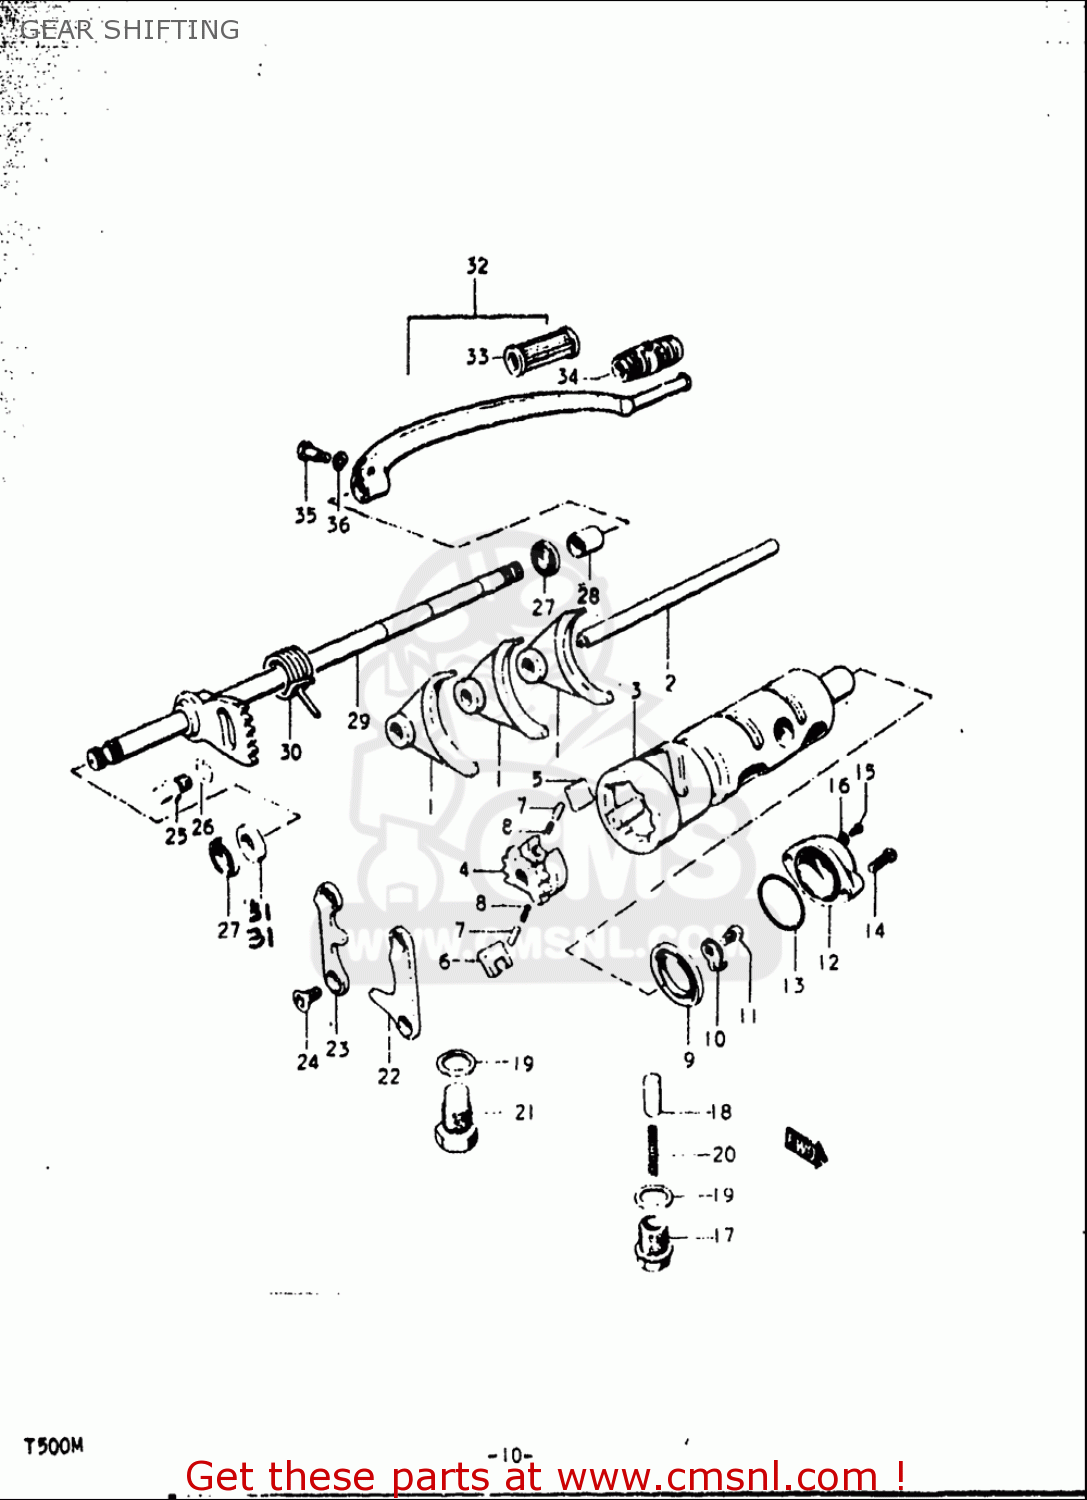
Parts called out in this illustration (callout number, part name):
4	GEAR,GEAR SHIFT CAM DRIVEN
5	PAWL,GEAR SHIFT NO.1
6	PAWL,GEAR SHIFT NO.2
7	PIN(5X8)
8	SPRING
9	SEAL,OIL(16X30X8)
10	CONTACT,GEAR SHIFT SWITCH
11	SCREW
12	BODY,GEAR SHIFT SWITCH
13	O RING(D:1.9,ID:27.7)
14	SCREW
15	SCREW
16	WASHER
17	HOUSING,GEAR SHIFT CAM STOPPER
18	STOPPER,REVERSE CAM
19	GASKET, STOPPER HOUSING
20	SPRING
21	BOLT
22	LIFTER,GEAR SHIFT PAWL
23	GUIDE,GEAR SHIFT
24	SCREW
25	STOPPER,GEAR SHIFT ARM
26	WASHER,LOCK
27	SEAL,OIL (12X22X9)
28	CUSHION
30	SPRING
32	LEVER ASSEMBLY,GEAR SHIFTING
33	RUBBER,GEAR SHIFT PEDAL
34	RUBBER,GEAR SHIFT PEDAL
35	BOLT
36	WASHER,LOCK
